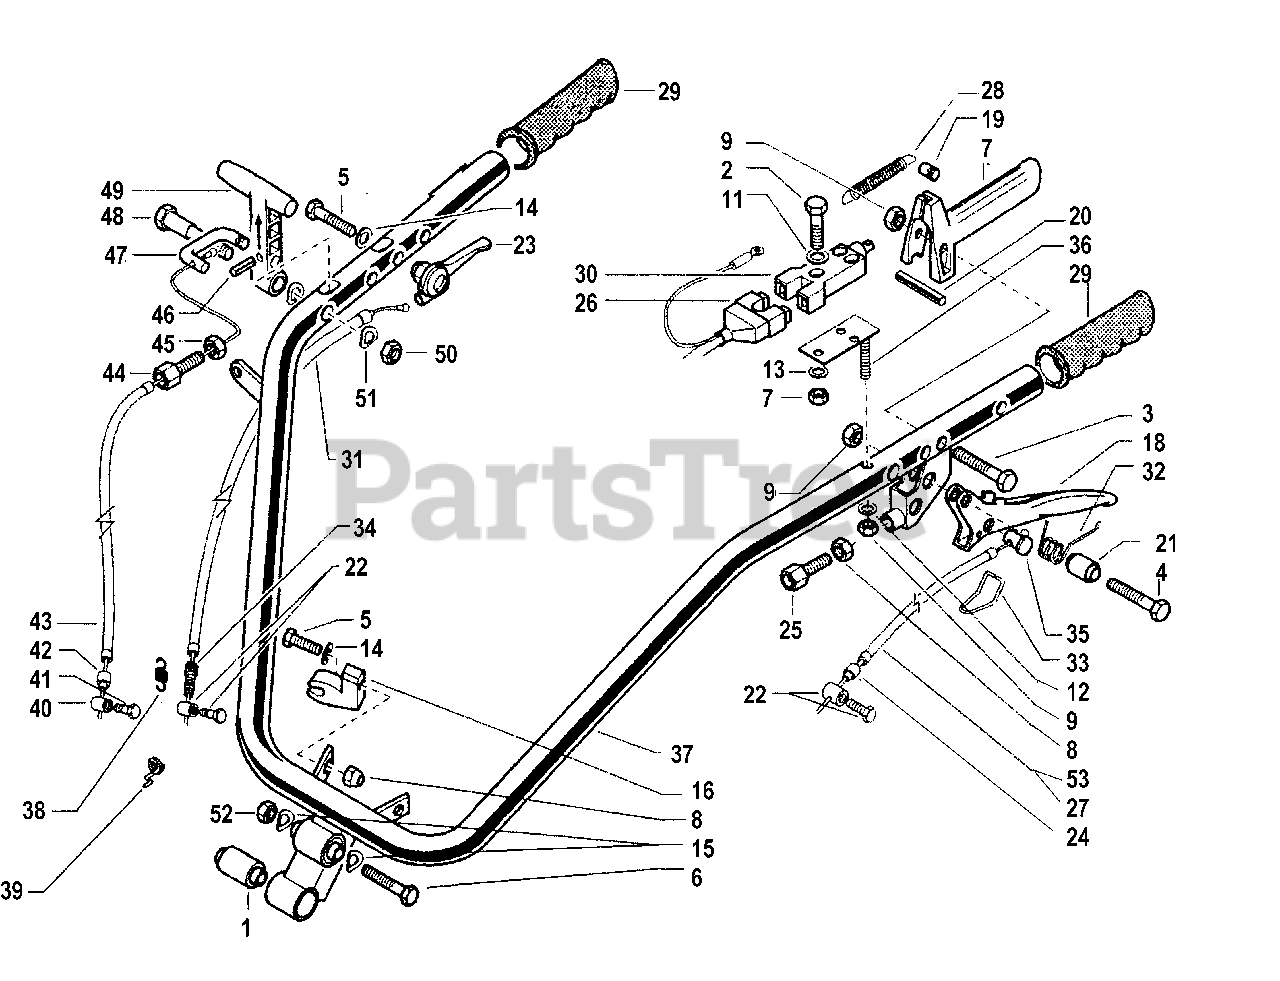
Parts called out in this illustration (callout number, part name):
1	SILENTBLOCK
2	SCREW TE M4X25
3	SCREW, TE M6X45
4	SCREW, M6X25
5	SCREW, M8X35
6	SCREW, M10X80
9	NUT, SELF LOCKING M6
11	FLAT WASHER, M4.3
12	WASHER, FLAT 6.4
13	LOCK WASHER, M4.3
14	WASHER, M8.4
15	WAVE WASHER, M10.4
16	SUPPORT, CONTROL ROD
17	MOTOR STOP LEVER
18	CLUTCH LEVER
20	LEVER STOP FOR MOTOR STOP
21	LEVER SPACER
22	CLAMP, CABLE
23	THROTTLE LEVER
25	SCREW, ADJUSTING, M8
26	SWITCH WIRING HARNESS
27	CLUTCH CABLE
30	STOP SWITCH
31	THROTTLE CABLE
32	LEVER SPRING
34	CABLE ADJUSTER
36	SWITCH PLATE
37	HANDLE BAR
40	CABLE CLAMP PIN
41	CAPSCREW M6X14
43	REVERSER CABLE
44	ADJUSTING SCREW
46	SPLIT PIN 4X20
47	PIN, REVERSER CABLE
49	LEVER, REVERSER
50	NUT, SELF LOCKING M8
51	WASHER LOCK
52	NUT, SELF LOCKING M10
53	CABLE, CLUTCH ELECTRIC STAR
